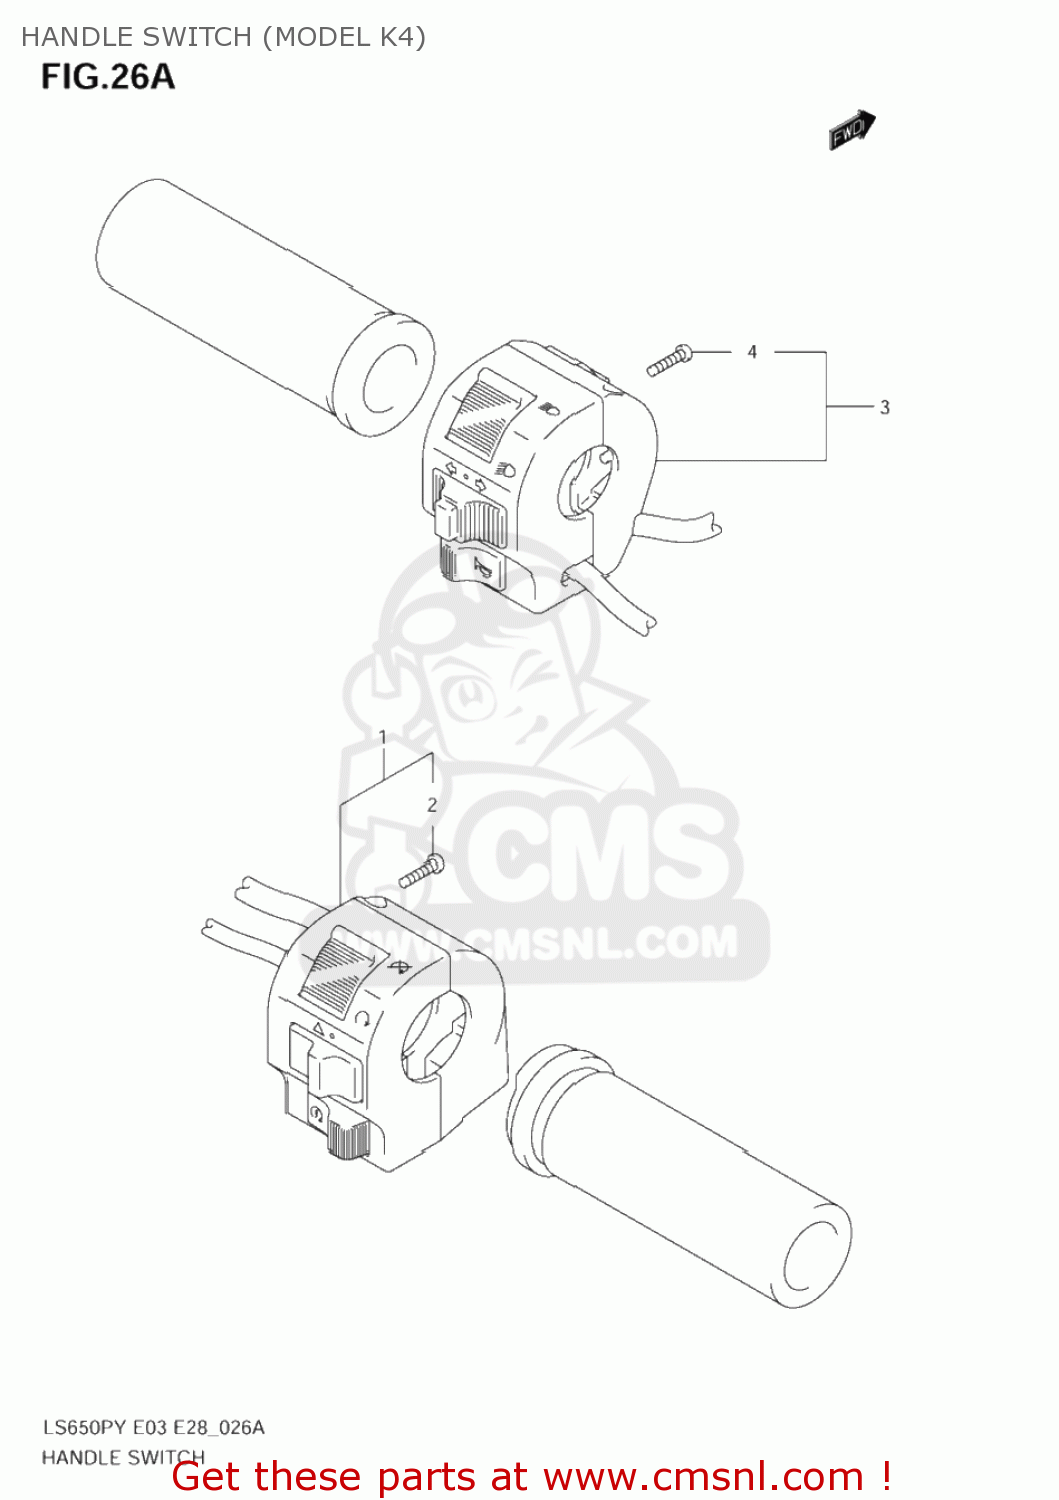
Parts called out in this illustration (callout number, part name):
1	SWITCH ASSY,HANDLE,R
2	SCREW
3	SWITCH ASSY,HANDLE,L
4	SCREW
